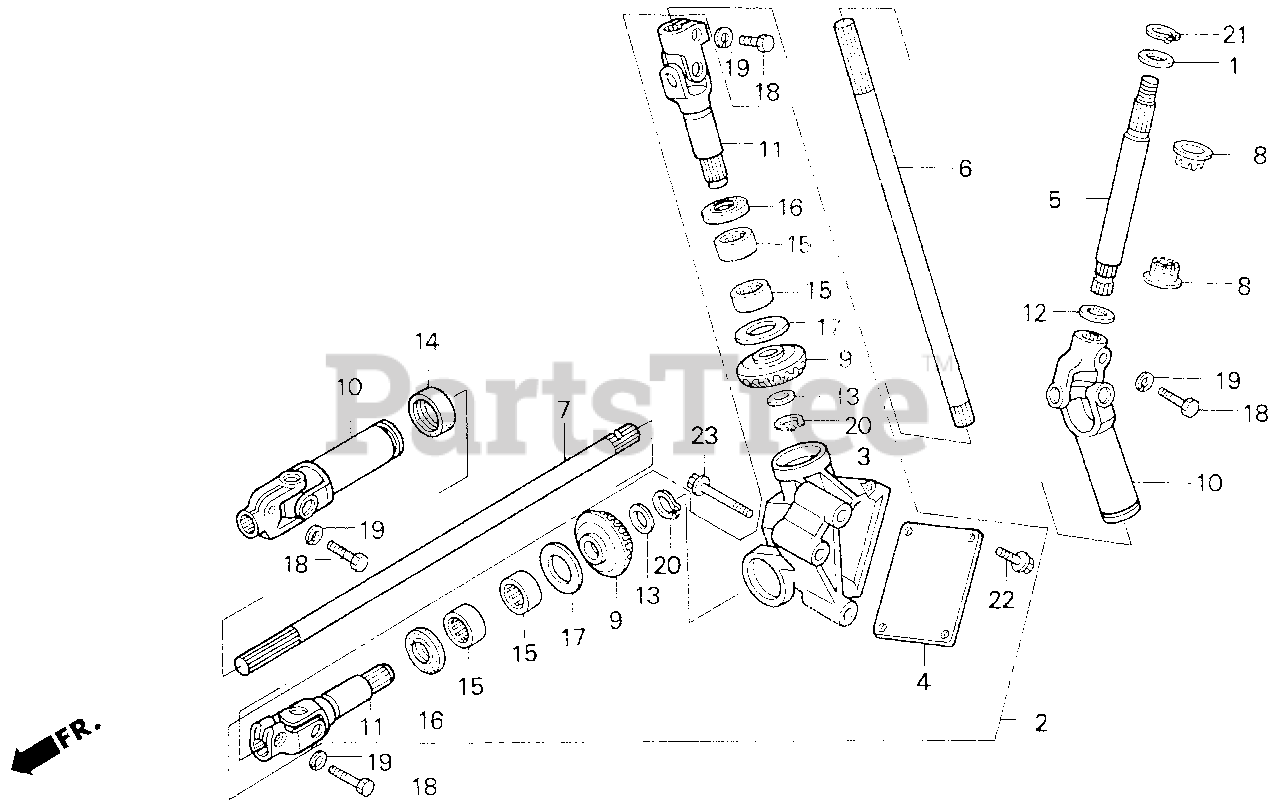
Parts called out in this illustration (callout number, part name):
1	SEAT, FR. RUBBER SPRING
2	GEAR ASSY., STEERING BEVEL
3	CASE, STEERING BEVEL GEAR
4	COVER, BEVEL GEAR CASE
5	SHAFT A, STEERING
6	SHAFT B, STEERING
7	SHAFT C, STEERING
8	BUSH A, STEERING SHAFT
9	GEAR, STEERING BEVEL
10	JOINT ASSY., STEERING
11	JOINT, STEERING BEVEL GEAR
12	WASHER, PLAIN (16MM)
13	WASHER, THRUST (14MM)
14	SEAL, SPLINE (16.5X21X0.75)
15	BEARING, NEEDLE (22X28X12)
16	DUST SEAL (22X35X7)
17	WASHER A, THRUST (26.5X40X2.00)
17	WASHER B, THRUST (26.5X40X2.15)
17	WASHER C, THRUST (26.5X40X2.30)
18	BOLT, HEX. (8X28)
19	WASHER, SPRING (8MM)
20	CIRCLIP (OUTER) (14MM)
21	CIRCLIP (OUTER) (18MM)
22	BOLT, FLANGE (6X16)
23	BOLT, FLANGE (8X50)
